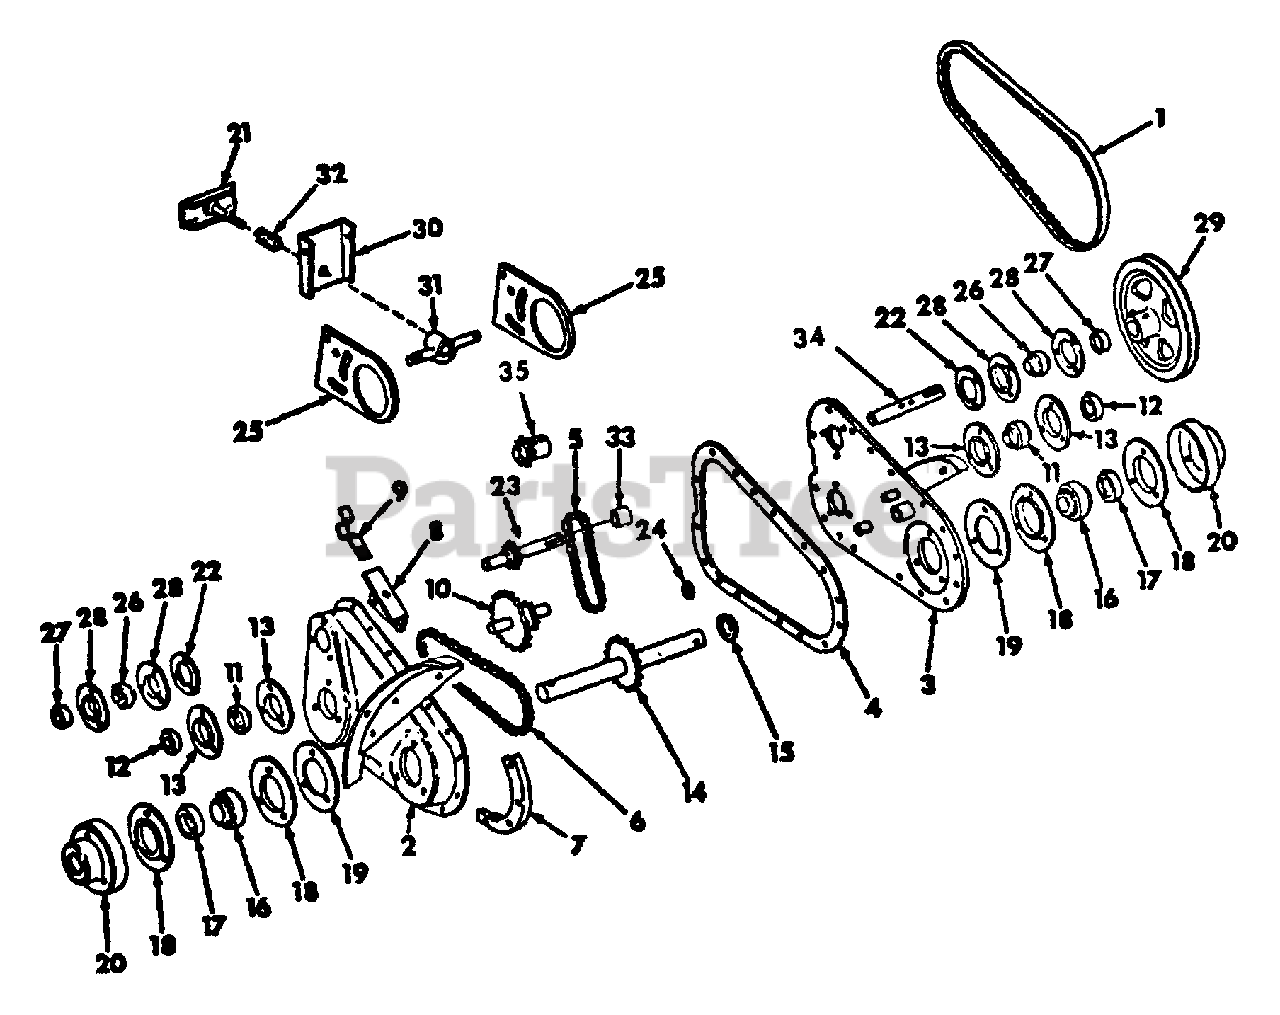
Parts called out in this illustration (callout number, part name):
1	BELT, DRIVE
2	HOUSING ASSY, CHAIN DRIVE
3	PLATE, HOUSING BACK
4	GASKET, CHAIN DRIVE HOUSING
5	CHAIN, MAIN DRIVE
6	CHAIN, TINE DRIVE
7	SHOE, FORMED
8	CLIP, MOUNTING BRACKET
9	CLIP, RETAINER
10	SPROCKET ASSY, IDLER 10 & 28 T (TEETH)
11	BEARING ASSY. w/o LOCKING COLLAR
12	COLLAR, LOCKING w/SET SCREW
13	FLANGE, BEARING
14	SHAFT ASSY, MAIN DRIVE 18 T (TEETH)
15	SPACER
16	BEARING w/o LOCKING COLLAR
17	COLLAR, LOCKING w/SET SCREW
18	FLANGE, BEARING
19	GASKET, FLANGE
20	DUST EXCLUDER
21	TEE ASSY, BELT ADJUSTMENT
23	SHAFT, INPUT
24	SEAL, ADHESIVE DUST
25	PLATE, PIVOT
26	BEARING w/o LOCKING COLLAR
27	COLLAR LOCKING
28	FLANGE BEARING
29	PULLEY, DRIVE
30	CHANNEL, BELT TIGHTENER
31	ADJUSTMENT ASSY
32	SPRING, COMPRESSION
33	SPACER, INPUT SHAFT
34	SHAFT, INPUT
35	SPROCKET 12 T FOR 1 TILLER
12872-R1	BOLT, 5/16-18 x 1 C-Z SQ-NK CRG
18627-R1	BOLT, 1/4-20 x 3/4 C-Z SQ-NK
21324-R1	KEY, 3/16 x 1-5/8 SQ PARALLEL
102581	SCREW, 5/16-18 x 3/8 SOC-HD CUP PT
120386	WASHER, 5/16 x 3/4 x .051 C-Z
